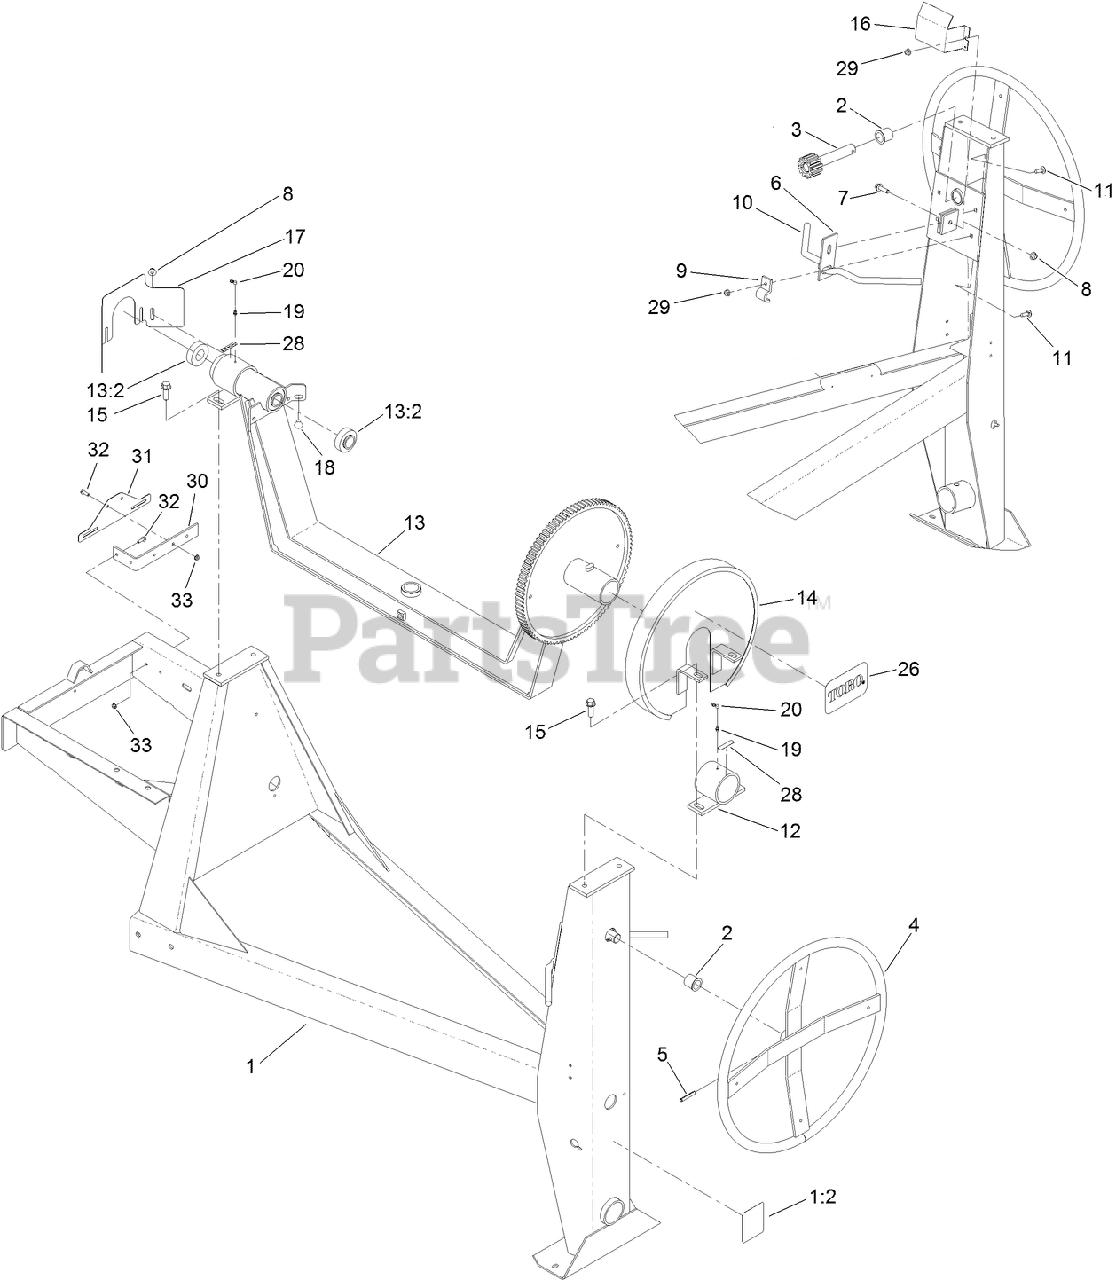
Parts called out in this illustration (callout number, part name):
1	FRAME ASM
1:2	DECAL-SAFETY CHAIN, TOWING
2	BUSHING-NYLON
3	SHAFT-TILT
4	HANDWHEEL
5	PIN-ROLL
6	DOG-BRAKE
7	SCREW-HHF
8	NUT-HF, NI
9	BRACKET-HANDLE
10	HANDLE-BRAKE
11	BOLT-CARR
12	TRUNNION
13	YOKE ASM
13:2	Bearing
14	GUARD-BRAKE, UPPER
15	SCREW-HWH
16	GUARD-BRAKE, LOWER
17	GUARD-PINION
18	SCREW-CARR
19	FITTING-GREASE
20	CAP-PLUG
26	DECAL
28	DECAL-GREASE
29	NUT-HF, NI
30	BRACKET-UNIVERSAL
31	HOLDER-PLATE, LICENSE
32	SCREW-HHF
33	NUT-KEPS
